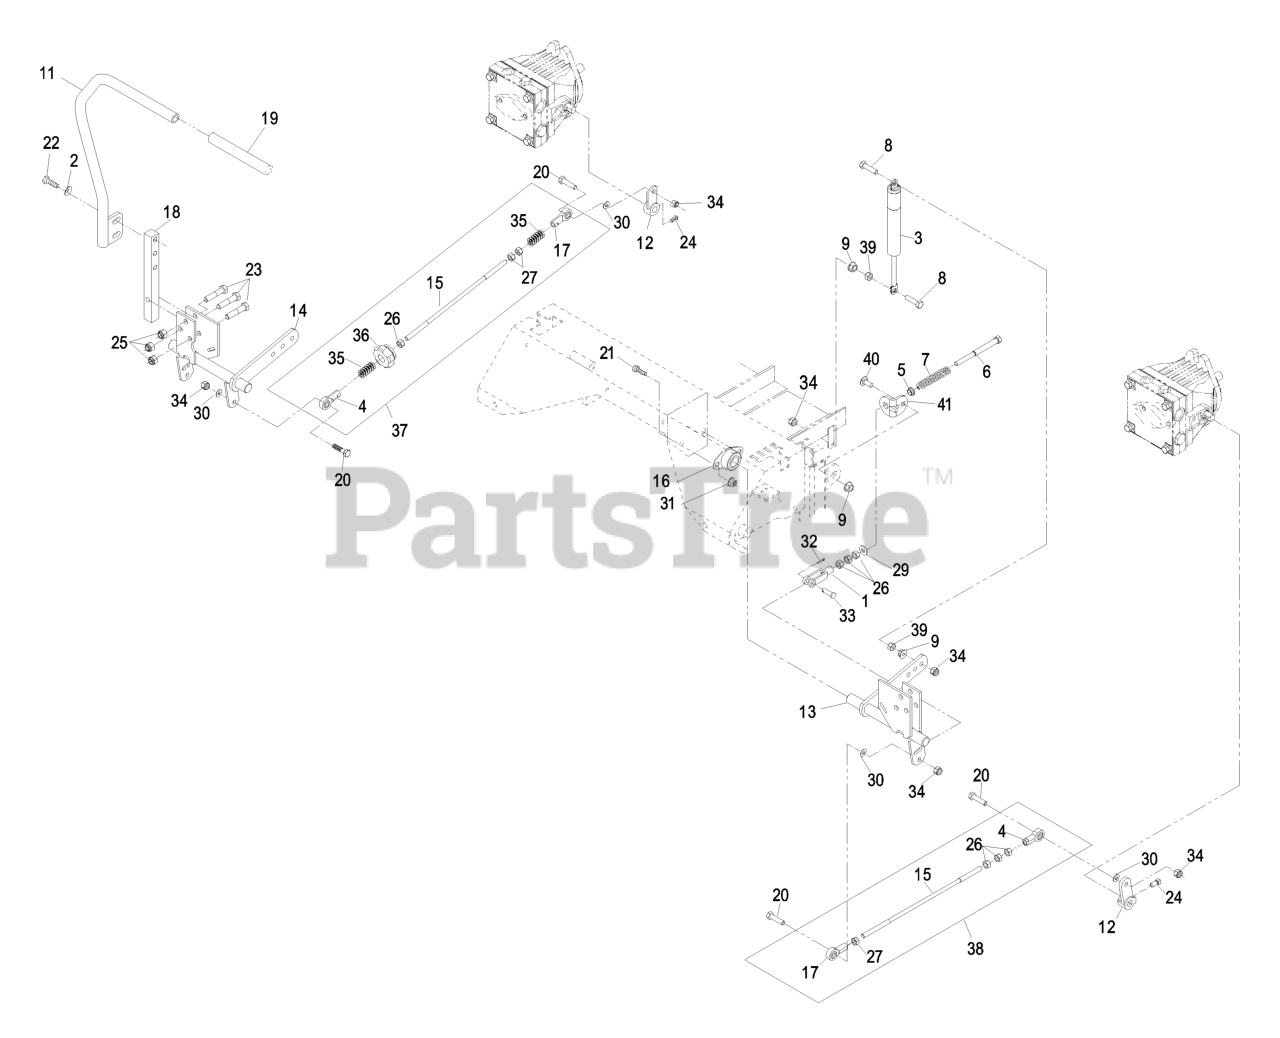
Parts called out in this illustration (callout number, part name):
1	YOKE-ADJUSTABLE
2	WASHER-BELLEVILLE
3	DAMPER-CONTROL, MOTION
4	BALLJOINT-RH
5	BUSHING-FLANGED
6	BOLT-RETURN, NEUTRAL
7	SPRING-RETURN, NEUTRAL
8	SCREW-HH
11	ASM.RH LEVER/GRIP
12	ARM-CONTROL, PUMP
13	CONTROL-MOTION, LH
15	LINK-ROD, TRACKING
16	BEARING-FLANGE, SIDE
17	BALLJOINT-LH
18	ARM-SHAFT, CONTROL
19	GRIP,CONTROL LEVER
20	SCREW-HH
21	SCREW-HH
22	SCREW-HH
23	SCREW-HH
24	SCREW-SET
25	NUT-LOCK, NI
26	NUT-HEX
28	NUT-JAM
29	WASHER-FLAT
30	WASHER-FLAT
31	NUT-HHF, WHIZ
32	PIN-COTTER
33	PIN-CLEVIS
34	NUT-LOCK, NI
35	SPRING-COMPRESSION
36	KNOB-TRACKING
37	TRACKING ROD ASM
38	TRACKING ROD ASM
39	NUT-HEX
40	SCREW-CARR
41	TAB-ADJUSTMENT
